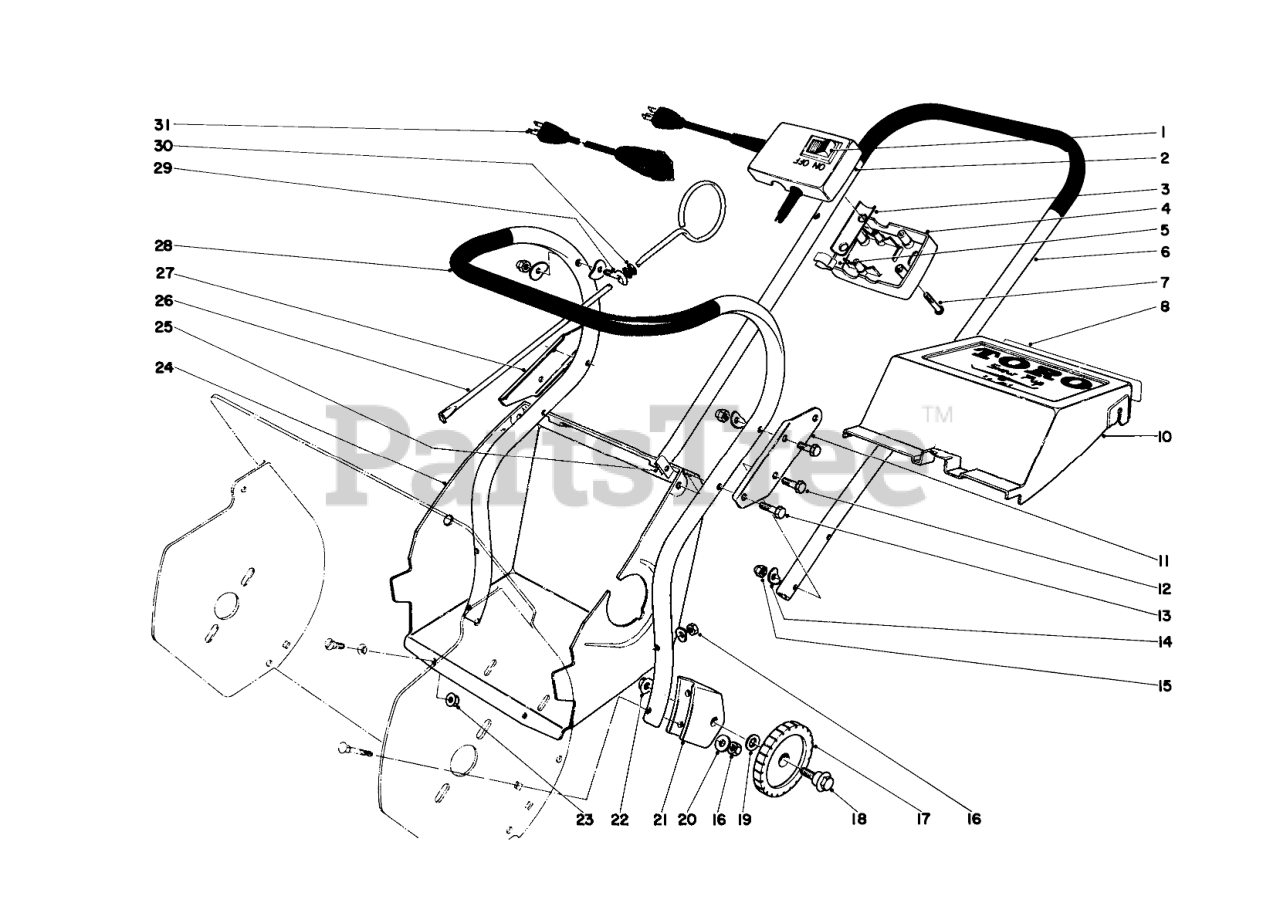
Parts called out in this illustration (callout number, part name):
1	Switch-Single Throw
2	Switch Housing Upper
3	Insert Switch Housing
4	Switch Housing Lower
6	Upper Handle
8	Decal
10	Shroud-Upper w/Decal
11	SPLICE PLATE
14	WASHER
15	NUT-CAP
16	Nut
17	Wheel
18	Bolt-Shoulder
19	WASHER-PLAIN
20	WASHER-FLAT
21	Bracket Wheel
22	NUT-HHF
23	NUT-LOCK, FLANGE
24	Lower Shroud
25	NUT-SPEED
26	Vane Adj. Rod
27	Plate-Splice
28	Handle Lower
29	Bolt-Eye
30	GROMMET
31	100 Ft. Cord
